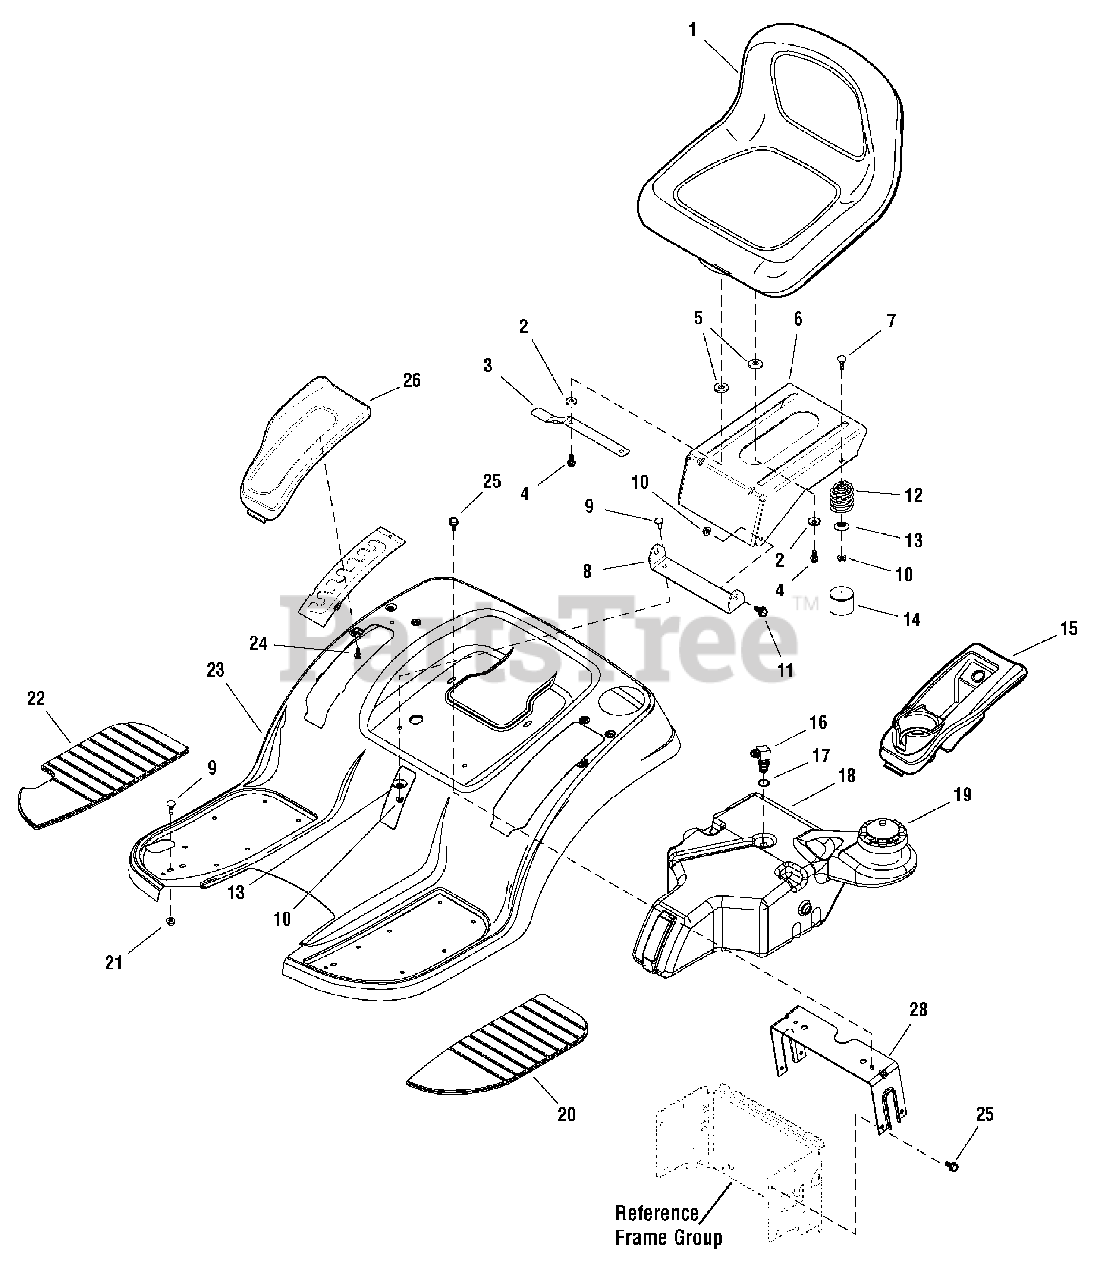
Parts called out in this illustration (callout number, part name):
1	SEAT, Low Back
1	SEAT, Hi Back, Steel Pan
2	WASHER, Plain, 5/16
3	LATCH, Seat 20GA E-Coat
4	CAPSCREW, Hex Head Flange Dog Point, 5/16-18 x 1
5	SPACER, Powdered Metal Yellow
6	SUPPORT, Seat 12GA
7	BOLT, Carriage, 5/16-18 x 3/4
8	PIVOT, Seat 10GA
9	BOLT, Carriage, 5/16-18 x 3/4
10	NUT, Hex Flange, 5/16-18 ESNA
11	BOLT, Shoulder 5/16-18 G5
12	SPRING, Compression
13	WASHER, Spring Black
14	COVER, Spring
15	POD, LH Cup Holder
16	ELBOW FITTING
17	BUSHING
18	TANK, Fuel
19	CAP, Gas
20	PAD, Footrest LH
21	NUT, Hex, Flange Whizlock, 5/16-18
22	PAD, Footrest RH
23	DECK, Seat w/Footrests (Red)
24	SCREW, Hex, Washer Head, Plastite, 1/4-20 x 1/2
25	SCREW, Taptite, 5/16-18 x 5/8
26	POD, RH Lift Quadrant
28	SUPPORT, Seat Deck
